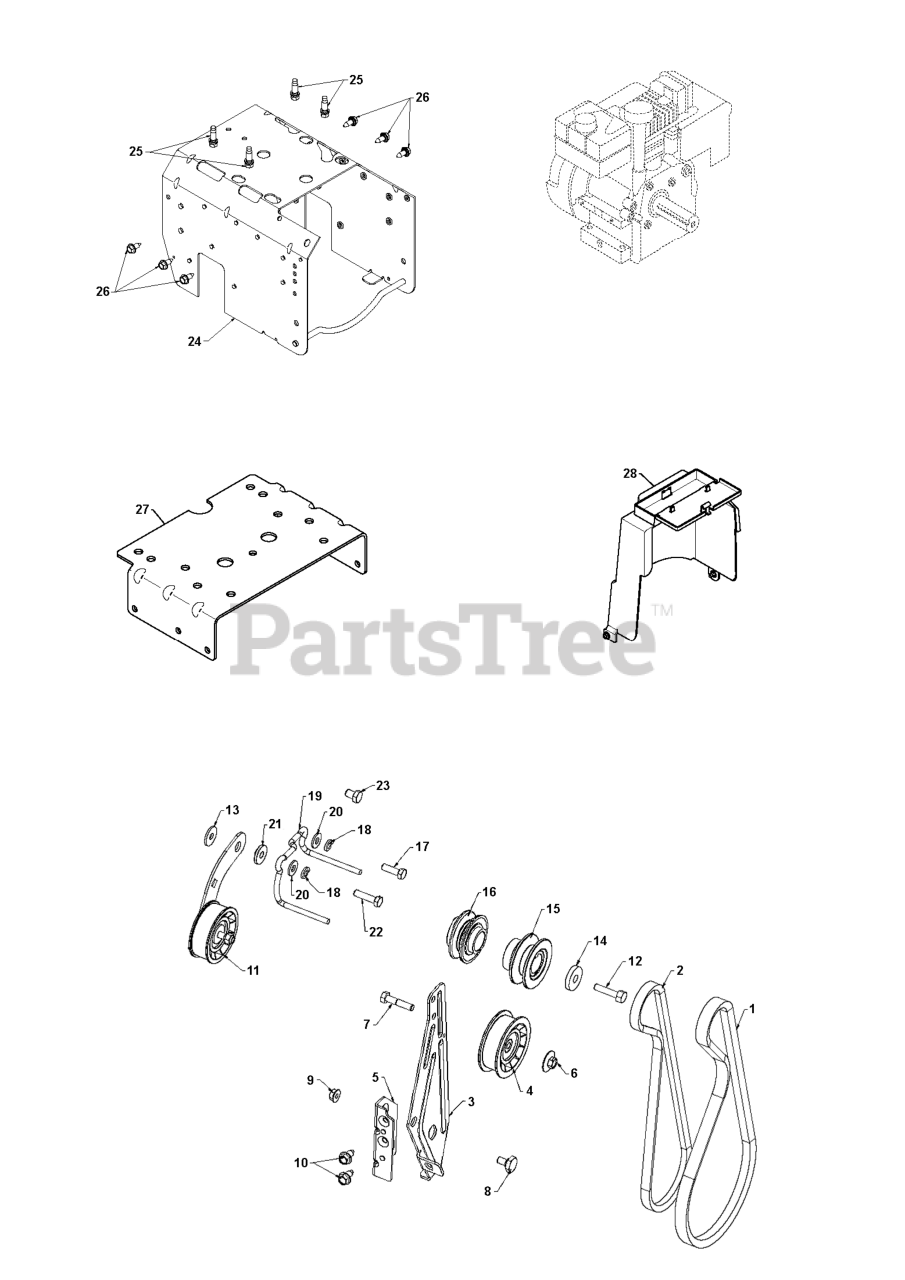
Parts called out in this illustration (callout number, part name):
1	V-BELT.IMPELLER
2	BELT.V.TRACTION.35.26
3	ARM.IDLER BRAKE.CLEAR.ZINC
4	PULLEY.W/SPACER.2.75
5	BRACKET.IDLER.PIVOT.ZINC
6	NUT.FLANGE.HEX.5/16X18.BLACK
7	HEX BOLT
8	BOLT.SHOULDER.1/2X12
9	NUT.LOCK.5/16-18
10	BOLT.5/16HEX.WHS.HD
11	ARM.ASM.TRACTION.IDLER.
12	BOLT.BLADE
12	SCREW, HEX HD 3/8-24 X 1-3/8
13	STEEL WASHER
14	WASHER.400X1.25X5.
15	PULLEY IMPELLER.ASM.2.60_.75 B
16	PULLEY TRACTION.ASM.2.60_.75 B
18	WASHER.LOCK.HVY.HLCL.SPR.5/16
19	GUIDE.BELT.CHAIN.LS.SNOW
20	WASHER.20X8.5
21	RP BUSHING, IDLER PIVOT
21	BUSHING.BRAKE.ARM
22	CAPSCREW.HEXHD.5/16X1.25.
23	SCREW.3/8-16 X .750 (2 2)
24	FRAME.WELD.HYDRO.668.PNT
25	BOLT 3/8-16X1-1/8
26	BOLT.HEX.HD.WASHER.5/16-18X.75
27	PLATE.ENGINE.MOUNT.LCT.ORANGE
28	COVER.ASM.BELT.EURO.HICR
